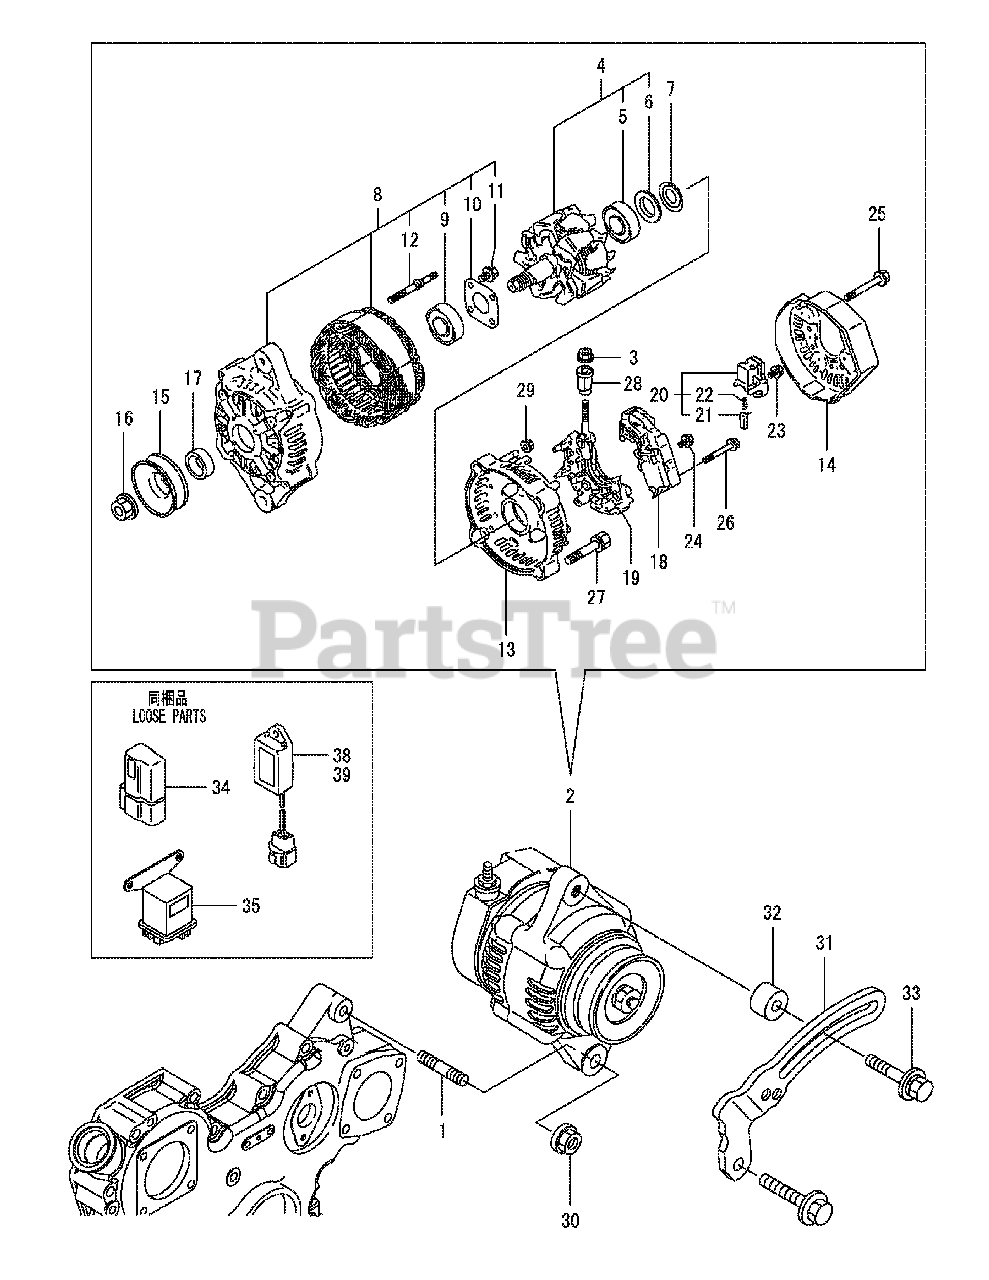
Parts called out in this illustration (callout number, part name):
2	Generator - Alternator, 40A
4	Rotor Assembly
8	Drive Flame Assembly
10	Retainer Plate
13	Rear Flame Assembly
14	Rear End Cover
18	Requlator Assembly
21	Brush Assembly
28	Insulation Bushing
35	Glow Relay
38	Timer, Glow Plug 15 sec
39	Timer, Fuel, 1 sec
